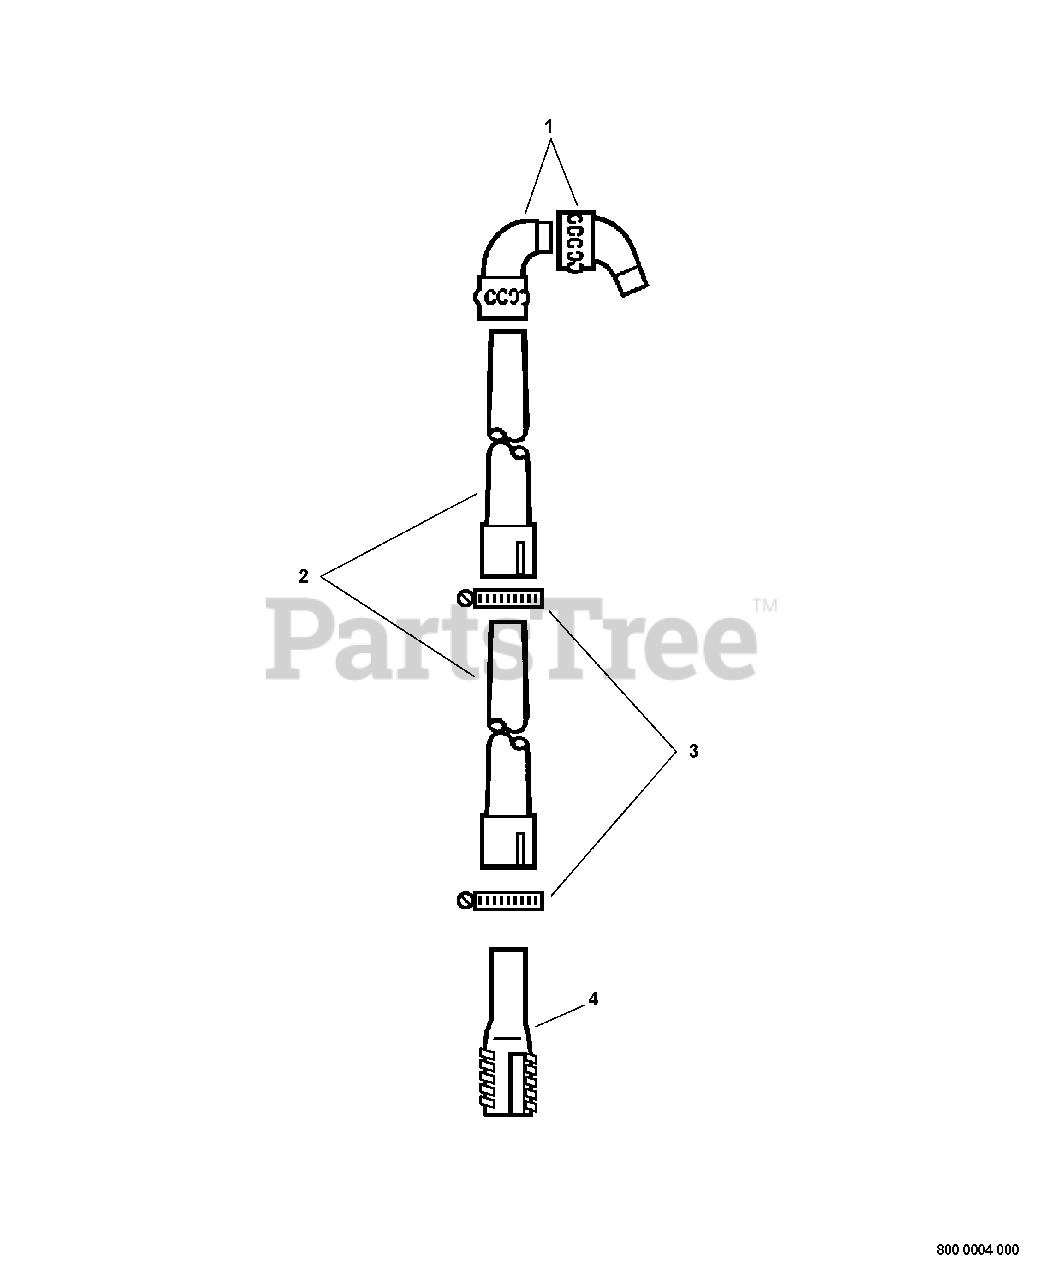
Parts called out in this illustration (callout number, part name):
1	TUBE, BLOWER - ELBOW
2	TUBE, BLOWER - STRAIGHT
3	CLAMP
4	ADAPTOR
